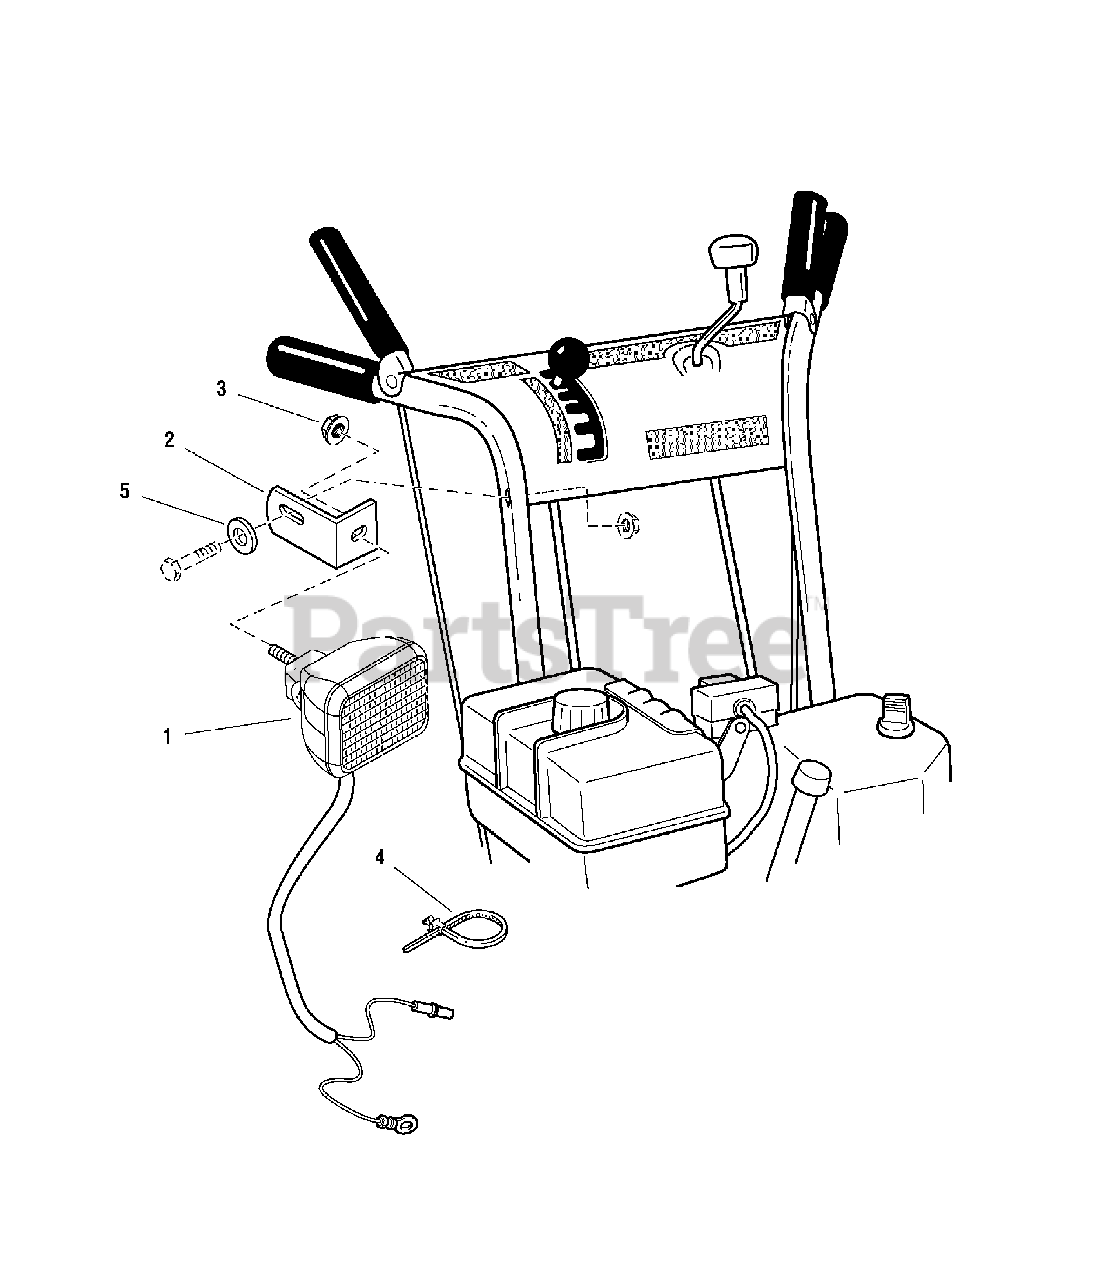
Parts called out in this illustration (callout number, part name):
1	HEADLIGHT ASSEMBLY, Clear Rectangle
2	STRAP, Torque
3	NUT, Hex Keps, 5/16-18, Conical Washer
4	TIE, Self Locking
5	WASHER, 5/16
